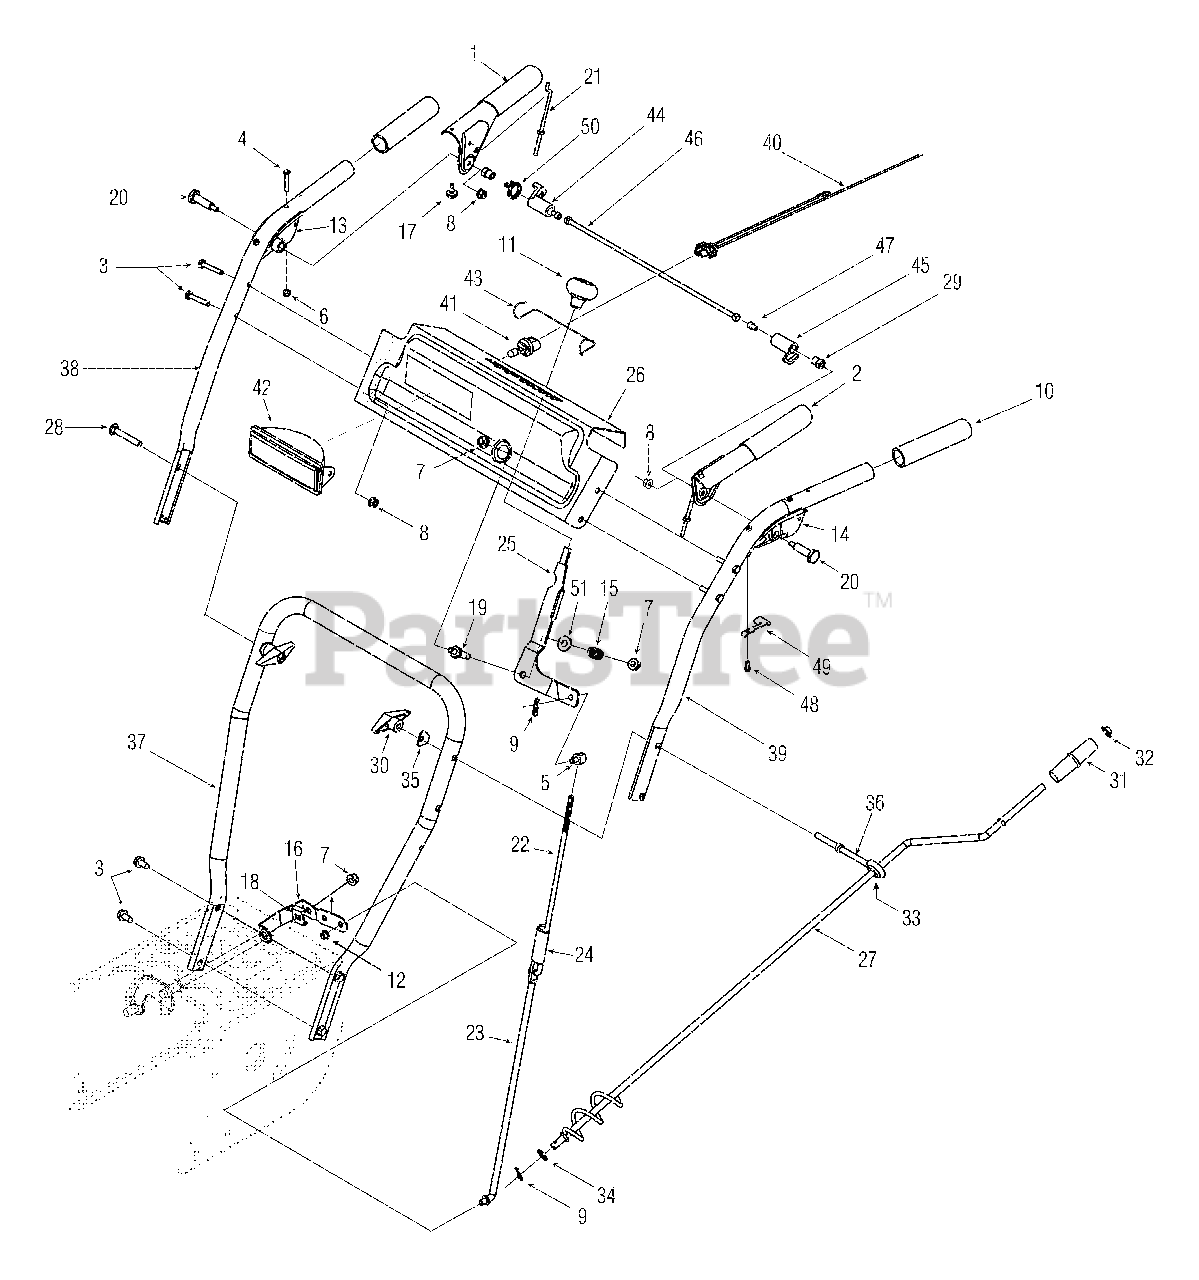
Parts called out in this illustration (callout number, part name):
1	Handle Ass'y, Engagement RH Black
2	Handle Ass'y, Engagement, LH Black
3	Screw, Self-tapping, 5/16-12, 0.750
4	Screw, Machine, #10-24, 1.375
5	Ferrule, 5/16-18 x .312 Diameter
6	Nut, Hex Lock, #10-24, Gr2, Nylon
7	Nut, Flange Lock, 5/16-18, Grf, Nylon
8	Nut, Flange Lock, 1/4-20, Grf, Nylon
9	Pin, Cotter, .072 Diameter x 1.13
10	Grip, 1.0 ID x 5.0
11	Shift Knob, Black
12	Nut, Push, 5/16
13	Handle, Clutch Lock, RH
14	Handle, Clutch Lock, LH
15	Spring, Compression, .39x.60 x .88
16	Spring, Shift, Lever
17	Bumper, Rubber, .62 OD x .22
18	Bracket, Shift Spacer
19	Bolt, Shoulder, 5/16-18 x 0.830
20	Screw, Shoulder, .437 x 1.345, 1/4-20
21	Z Fitting, Cable
22	Rod, Shift, Kit
23	Rod, Shift, Lower
24	Connector Sleeve, Shift Rod
25	Lever, Shift, Speed
28	Screw, Carriage, 5/16-18, 2.25, Gr5
29	Shoulder Nut, Hex, 1/4-20
30	Knob Assembly, Wing Nut, 5/16-18
31	Crank Knob, 1.0 Diameter x 3.2, Black
32	Cap, Push, 3/8 Rod
33	Grommet, .44 ID x .94 OD x .50
34	Washer, Flat, .375 x .738 x .063
35	Washer, Saddle, 320 x .93 x .060
36	Eye Bolt, Chute Crank
40	Harness, Headlight
41	Lamp, Halogen, 12V, 27W
42	Lens Assembly, Lamp
43	Retainer, Lens
44	Plate, Lock
45	Cam, Lock
46	Rod, Pivot
47	Screw, 1/4-20, .375
48	Screw, #8-18 x .50
49	Spring, Control Lever Lock
50	Spring, Torsion, .8156 x .3038
51	Washer, Flat, .385 x .870 x .092
